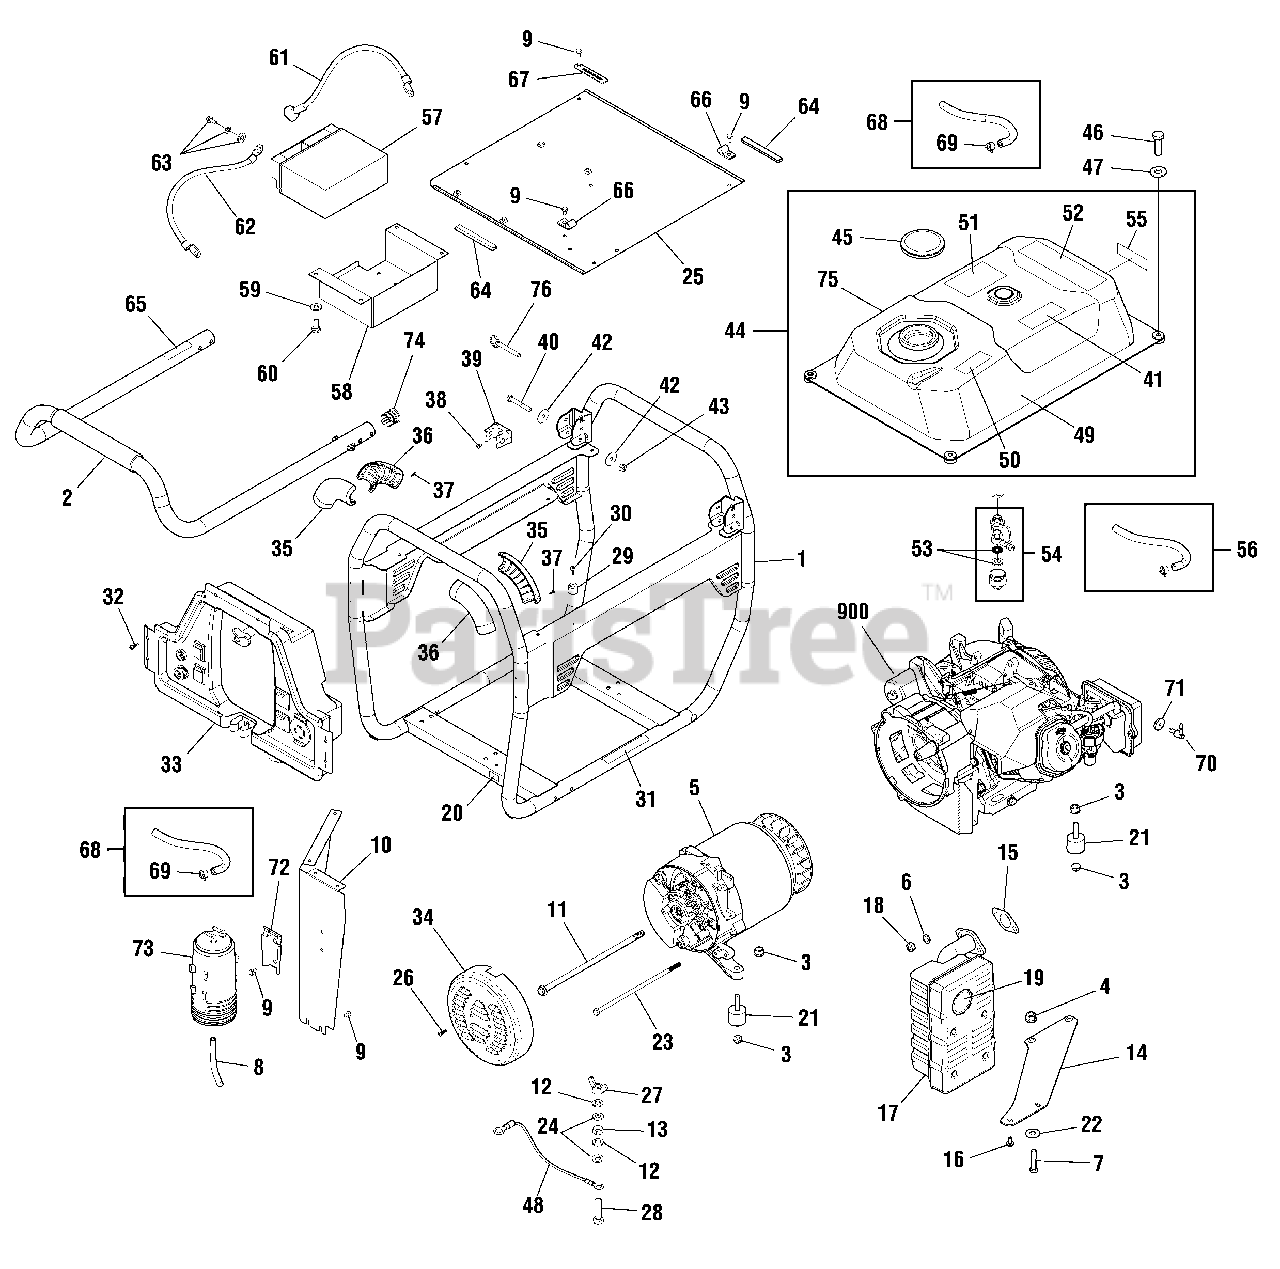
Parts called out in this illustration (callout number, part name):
5	ALTERNATOR
6	* WASHER-LOCK 3/8
7	* HHCS-M10-1.5 x 45
8	HOSE-FUEL
9	* HHCS-M6-1.0 x 10
12	* WASHER-LOCK 1/4
13	* NUT-M6-1.0
15	GASKET-EXHAUST
16	* HHCS-M6-1.0 x 12
18	* NUT-M8 - 1.25
21	MOUNT-VIBRATION
22	WASHER
24	* WASHER-M6
28	* HHCS-M6-1.0 x 25
34	COVER-REAR BEARING
41	DECAL
47	* WASHER-FLAT 1/4
53	KIT-FUEL VALVE REPAIR
56	KIT-FUEL HOSE (Cut to fit)
63	KIT-BATTERY HARDWARE
68	HOSE-VAPOR (Cut to fit)
900	** ENGINE
